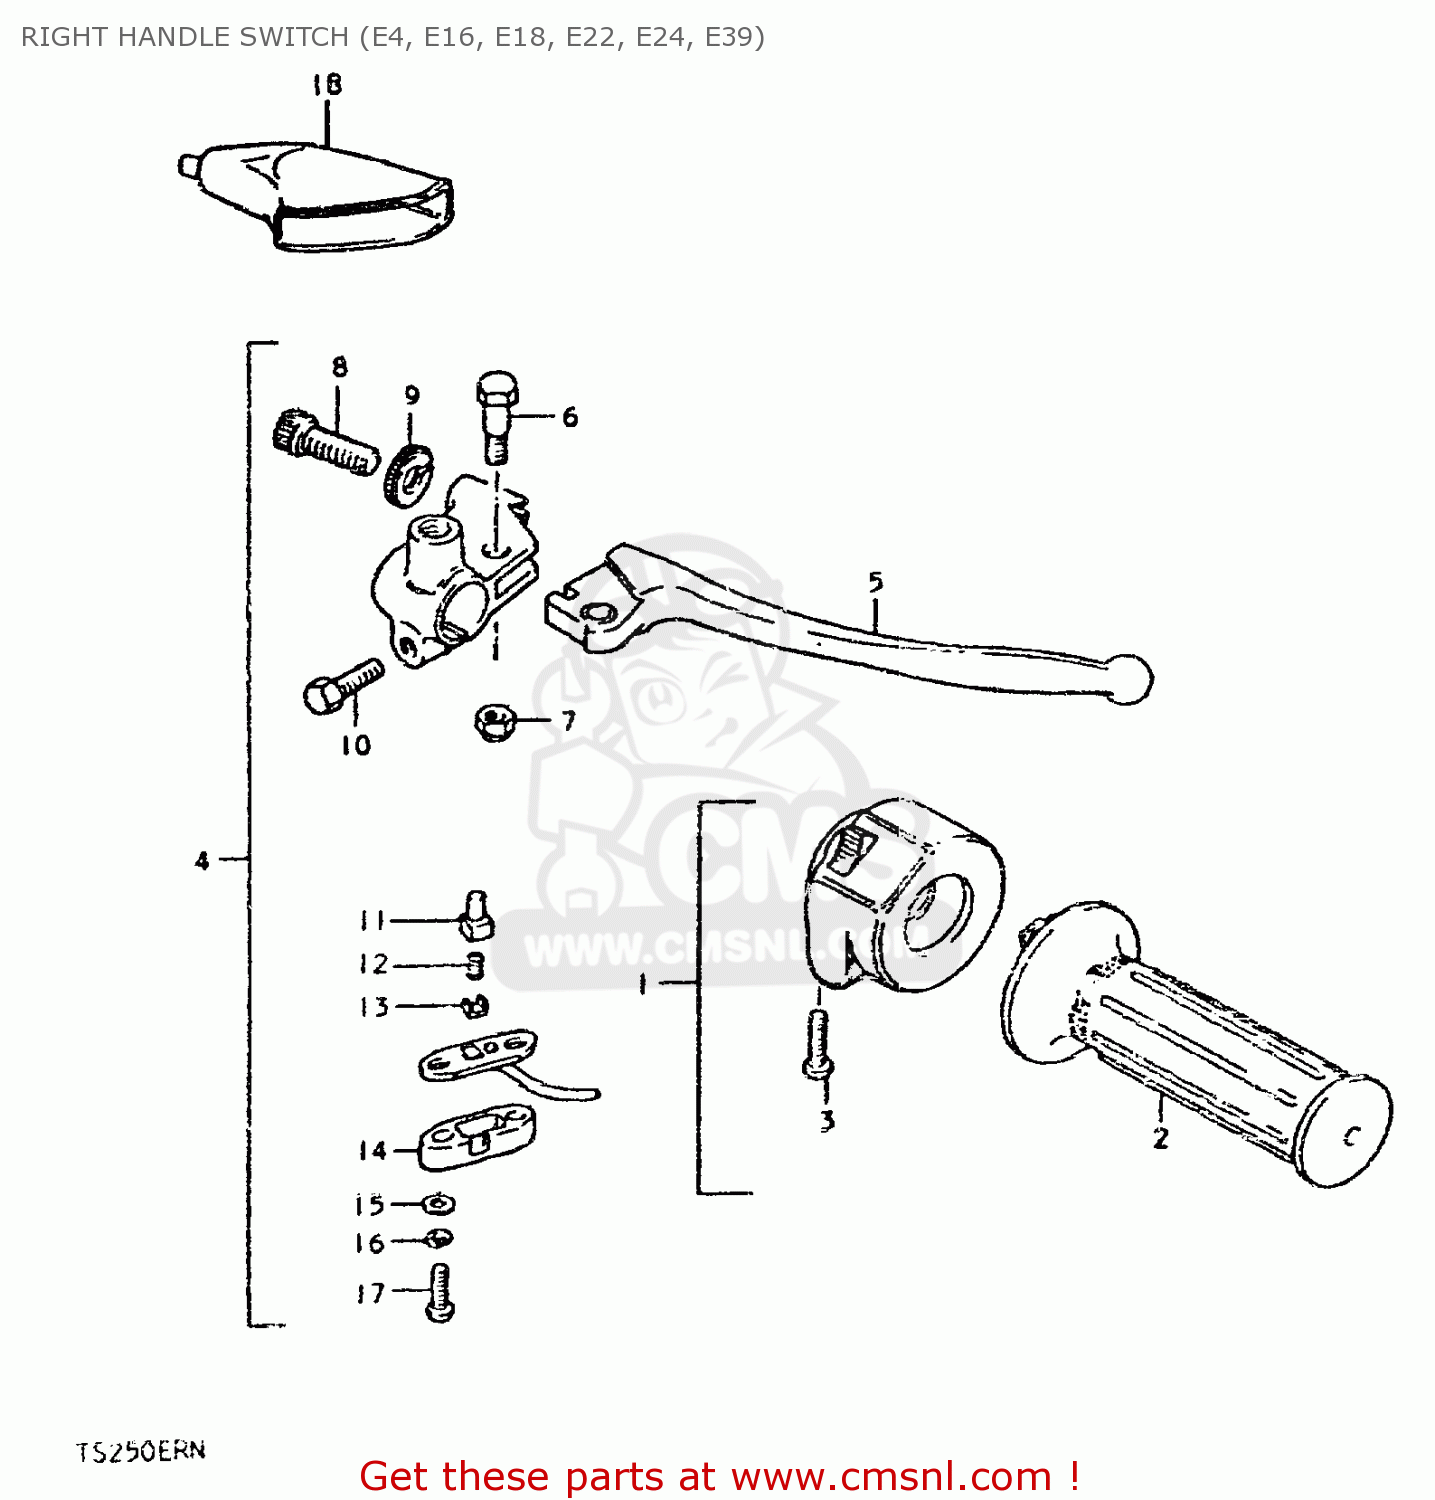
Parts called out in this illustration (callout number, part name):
1	CASE ASSEMBLY,THROTTLE
2	GRIP,THROTTLE
3	SCREW
4	BRAKE LEVER & SWITCH ASSY
5	LEVER,BRAKE
6	BOLT,LEVER
7	NUT 6MM
8	ADJUSTER,CABLE
9	NUT,CABLE ADJUSTER
10	BOLT
11	HOLDER
12	SPRING
13	PLATE
14	COVER,FR BK TERMINAL BASE
15	WASHER
16	LOCK WASHER
17	SCREW
18	COVER,CLUTCH LEVER
